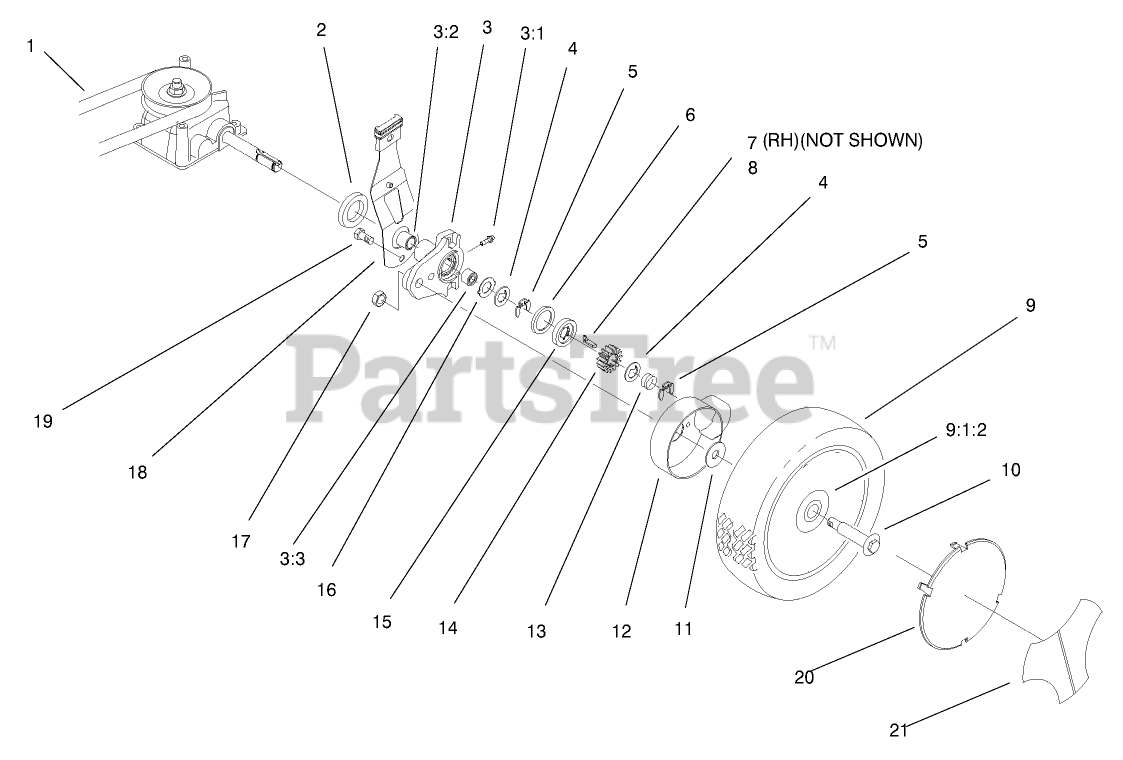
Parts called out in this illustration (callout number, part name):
1	V-BELT
2	SPACER-SHAFT, AXLE
3	REAR HEIGHT ADJUSTMENT ARM ASM
3:1	FITTING-GREASE
3:2	BUSHING
3:3	BUSHING
4	WASHER-THRUST, KEYED
5	RING-RETAINING,CLIP
6	RING-FRICTION
7	KEY-ROCKING, RH
8	KEY-ROCKING, LH
9	WHEEL AND TIRE ASM
9:1	Wheel ASM
9:1:2	BUSHING
10	BOLT-SHOULDER
11	WASHER-STEPPED
12	COVER-WHEEL
13	SPRING-COMPRESSION
14	GEAR-PINION
15	WASHER-CLUTCH
16	WASHER-ARM, PIVOT
17	LOCKNUT
18	REAR SPRING ARM ASM
19	SCREW-HWH
20	COVER-WHEEL, SMART
21	LABEL-WHEEL, SMART
